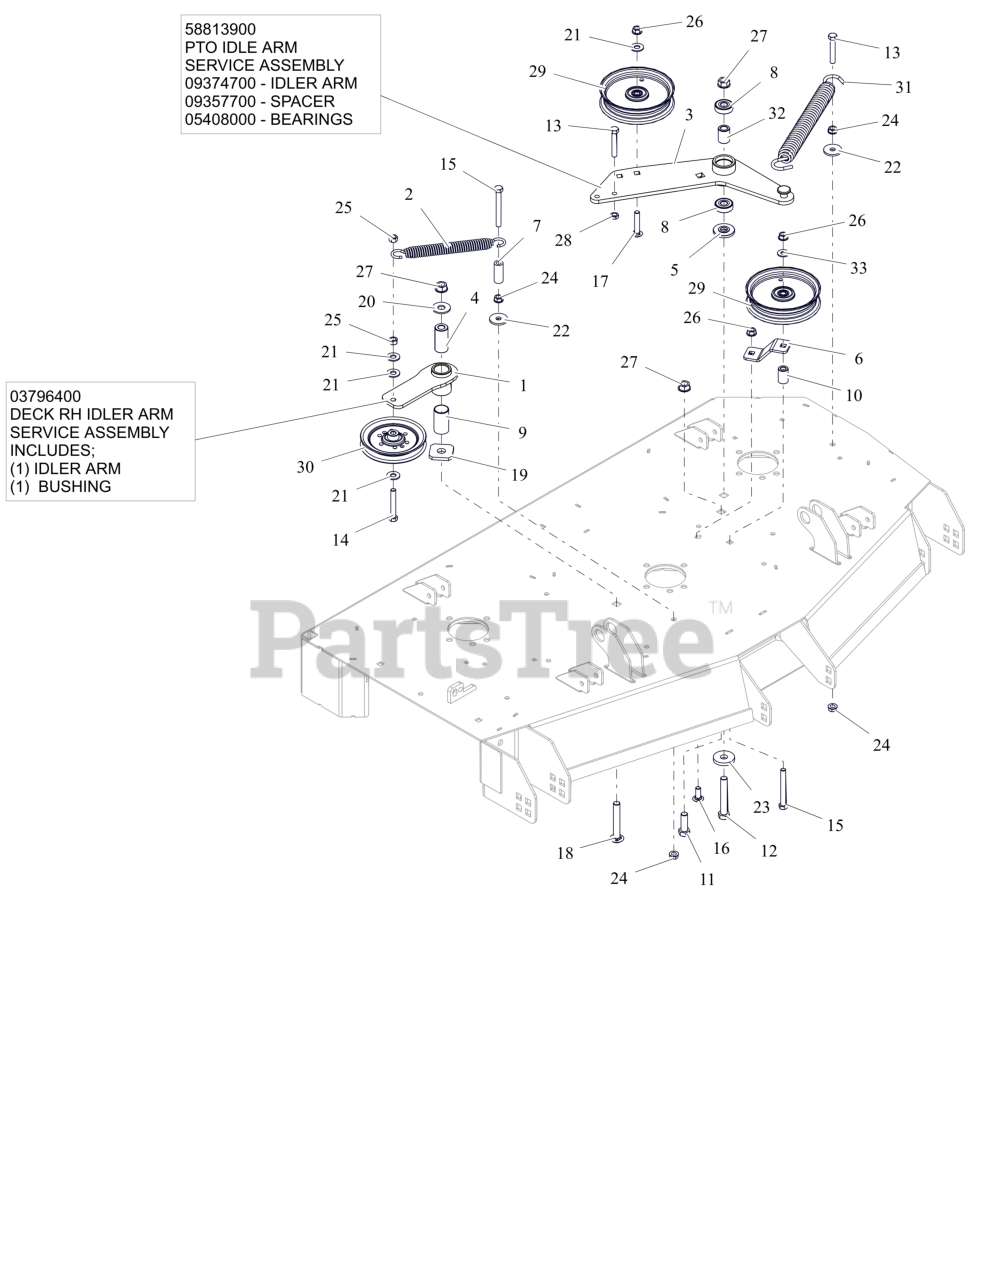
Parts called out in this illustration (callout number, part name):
1	WMT, IDLER ARM - BLACK
1	ASM, IDLER ARM (DECK)
2	SPRING- EXTENSION
3	WLDMT, IDLER ARM PT660
3	PTO IDLER ARM
3	SPACER .510 X .867 X 1.1485
3	BRG-BALL .500X1.38X.437
4	BSHG, SPCR .502X.997X2.03 PM
5	SPACER, IDLER ARM
6	PTO FIXED IDLER MTG BRKT -RED
7	HOSE, .38 X 1.65
8	BRG-BALL .500X1.38X.437
9	BSHG, 1.00X1.125X1.937
10	BUSHING, SLV .380X.750X1.190
11	BLT,HEX .50-13X1.50 G5 ZCC
12	BLT,HEX .50-13X3.25 G5 ZCC
13	BLT,HEX .38-16X2.25 G5 ZCC
14	BLT, HEX .38-16X2.50 G5 ZCC
15	BLT, HEX .38-16X3.25 G5 ZCC
16	BLT,RHSSN .38-16X1.00 G5 ZCC
17	BLT,RHSSN.375-16X2.00 G5 ZCC
18	BTL,RHSSN .500-13 X 3.25 G5 ZCC
19	WSHR-FLT .640X1.75X.250
20	WSHR,FLT .563X1.375X.109 ZCC
21	WSHR,FLT .438X1.00X.083 ZCC
22	WSHR,FLT .406X1.375X.135 ZCC
23	WSHR-FL-STL 0.557X1.625X0.25 ZCC
24	NUT, SPNLK-FLG .38-16 G5 ZCC
25	NUT-LK-CTR .38-16 ZC120
26	NUT-LK-CTR-FLG .375-16 GF ZCC
27	NUT-LK-CTR-FLG .500-13 GG ZCC
28	NUT-JAM .375-16 G2 ZCC
29	IDLER- FLAT - 5.00" X .75"
30	IDLER, V, 5.00X.38
31	SPRING, EXTENSION
32	SPACER .510 X .867 X 1.1485
33	WSHR,FLT .375X.875X.083 ZCC
